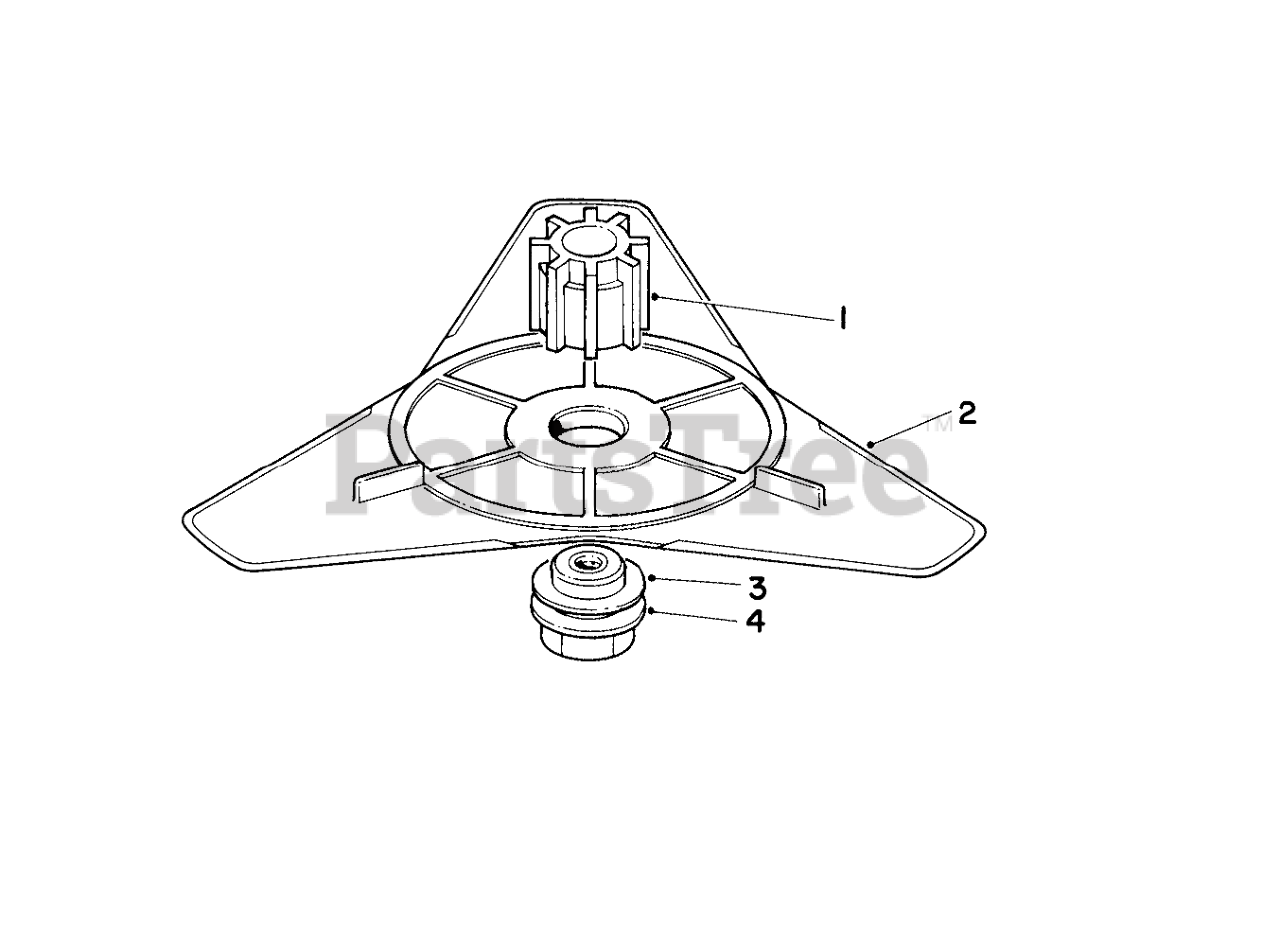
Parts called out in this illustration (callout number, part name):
1	BLADE ADAPTER
2	FLEX BLADE PKG
3	FLAT WASHER
4	ADAPTER NUT
